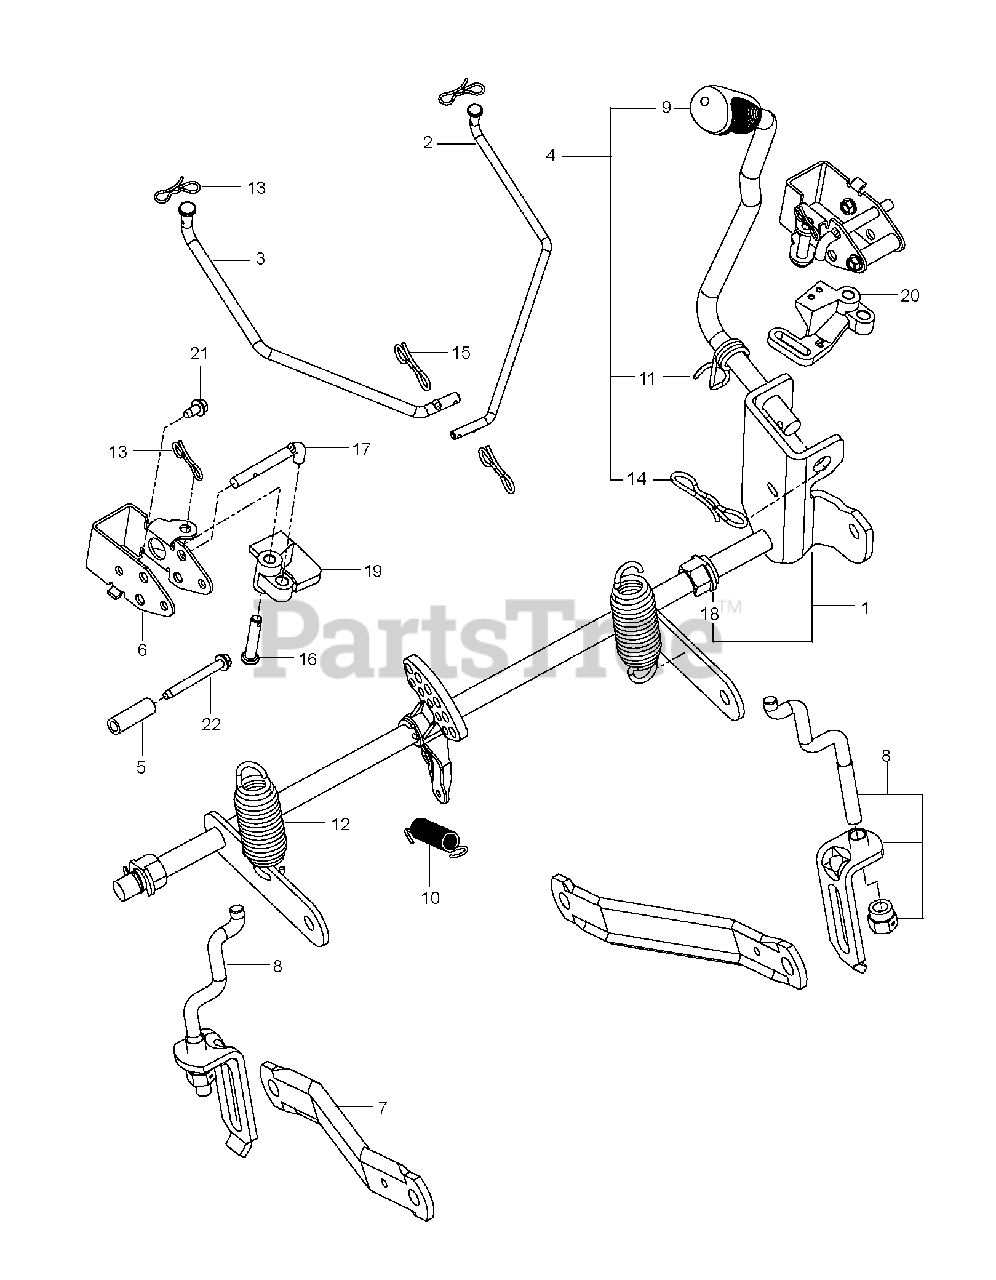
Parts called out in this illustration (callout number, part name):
1	SHAFT.ASM.RZ.DECK.LIFT.SRV
2	LINK.BRAKE.PARK.UPPER.LH
3	LINK.BRAKE.PARK.UPPER.RH
4	LIFT.LEVER.ASM.RZ.SERVICE
5	SPACER.334.ID.5.OD.1.5.L
6	BRACKET.BELLCRANK.PBRAKE X431
7	ARM.SUSPENSION.MOWER
8	LINK.ASM.RZ.LIFT.SERVICE
9	GRIP.HANDLE.LIFT.PVC.BLACK
10	RETURN.BRAKE.PARK.AUTO
11	SPRING.TORSION.LIFT.HANDLE
13	PIN COTTER;LOCKING;BOWTIE;1IN
14	PIN.COTTER.7/16.BOW TI.
15	PIN.COTTER.5/16.BOW TI
16	PIN.5.16X1.5
17	ROD.PUSH.BRAKE
18	PLASTIC NUT
19	BELLCRANK.RH
20	BELLCRANK.LH
21	SCREW.1/4-20X5/8
22	SCREW THD;ROLL;1/4-20 X 2.25
